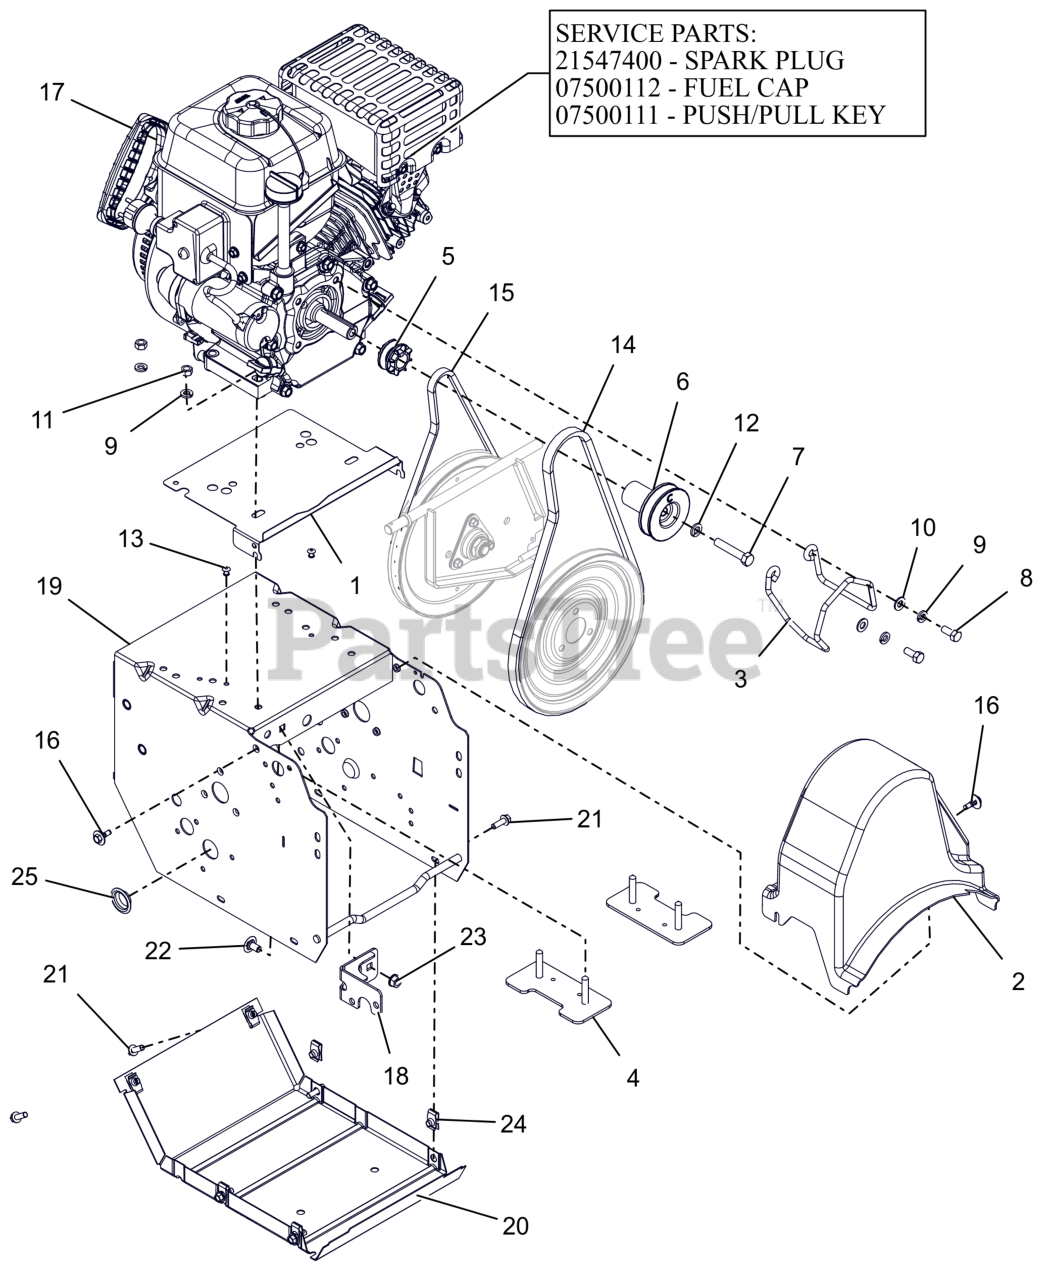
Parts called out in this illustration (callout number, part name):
1	BAFFLE, COMPACT
2	COVER, COMPACT BELT
3	FINGER, BELT
4	STRAP, ENGINE BOLT-WELDMENT
5	SHEAVE, TRACTION
6	SHEAVE, ATTACHMENT SINGLE GRV
7	BLT, HEX .38-24X2.00 G5 ZCC
8	BLT, HEX .31-24X.750 G5 ZCC
9	WSHR, LK-HVY .312X.097 ZCC
10	WSHR,FLT .344X.688X.065 ZCC
11	NUT, HEX .312-18 ZCC
12	WSHR,LK-REG .375X.094 ZCC
13	RVT, POP .1875 ZCC
14	V-BELT, HA-RAW EDGE
15	V-BELT, 3L-WRAPPED
16	SCR-TAP .25-20X.5 CAPTIVE
17	ENGINE, ARIENS AX208 240V/60W
17	PLUG, SPARK
17	CAP, FUEL TANK BLACK
17	KEY, PUSH/PULL LCT (2/PACKAGE)
18	WELDMENT, FRAME BRACKET
19	FRAME, MAIN
20	COVER, BOTTOM
21	BLT, HWH .25-20X.75 G5 ZCC
22	BLT, RHSSN .31-18X.625 G5 ZCC
23	NUT-LK-TOP-FLG .312-18 GF ZCC
24	NUT-RTNR .25-20X.56
25	PLUG, HOLE - 1.00" FLEXTEMP
